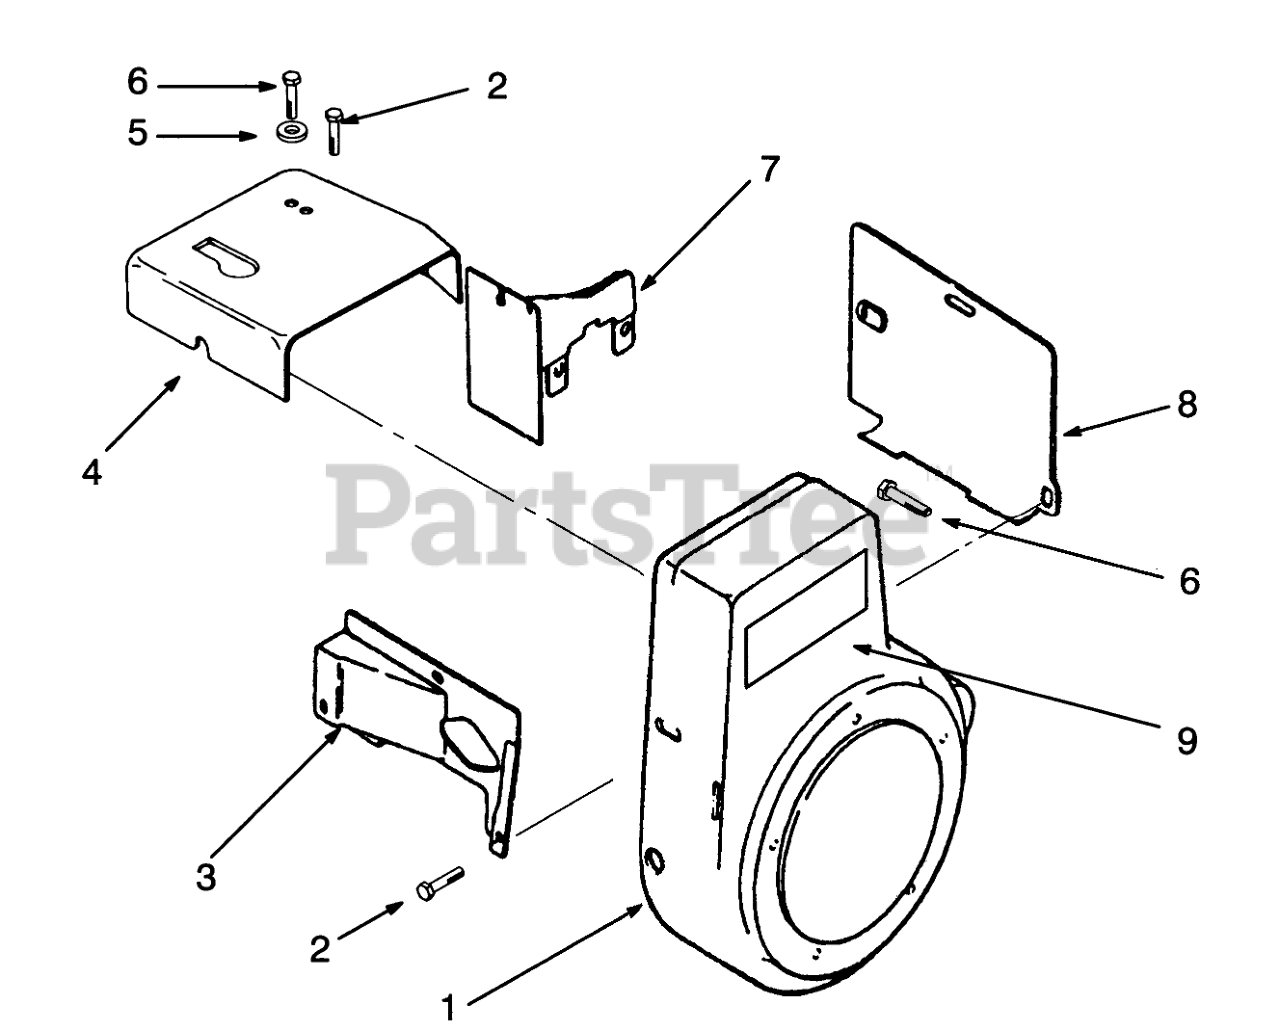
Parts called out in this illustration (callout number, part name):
1	Blower Housing
2	Screw Hex Hd
3	Baffle-SideAir
4	Baffle-Head
5	Washer
6	Screw-Pozidriv T.H.
7	Baffle-Inner
8	Baffle-Cylinder
9	Decal-HP
